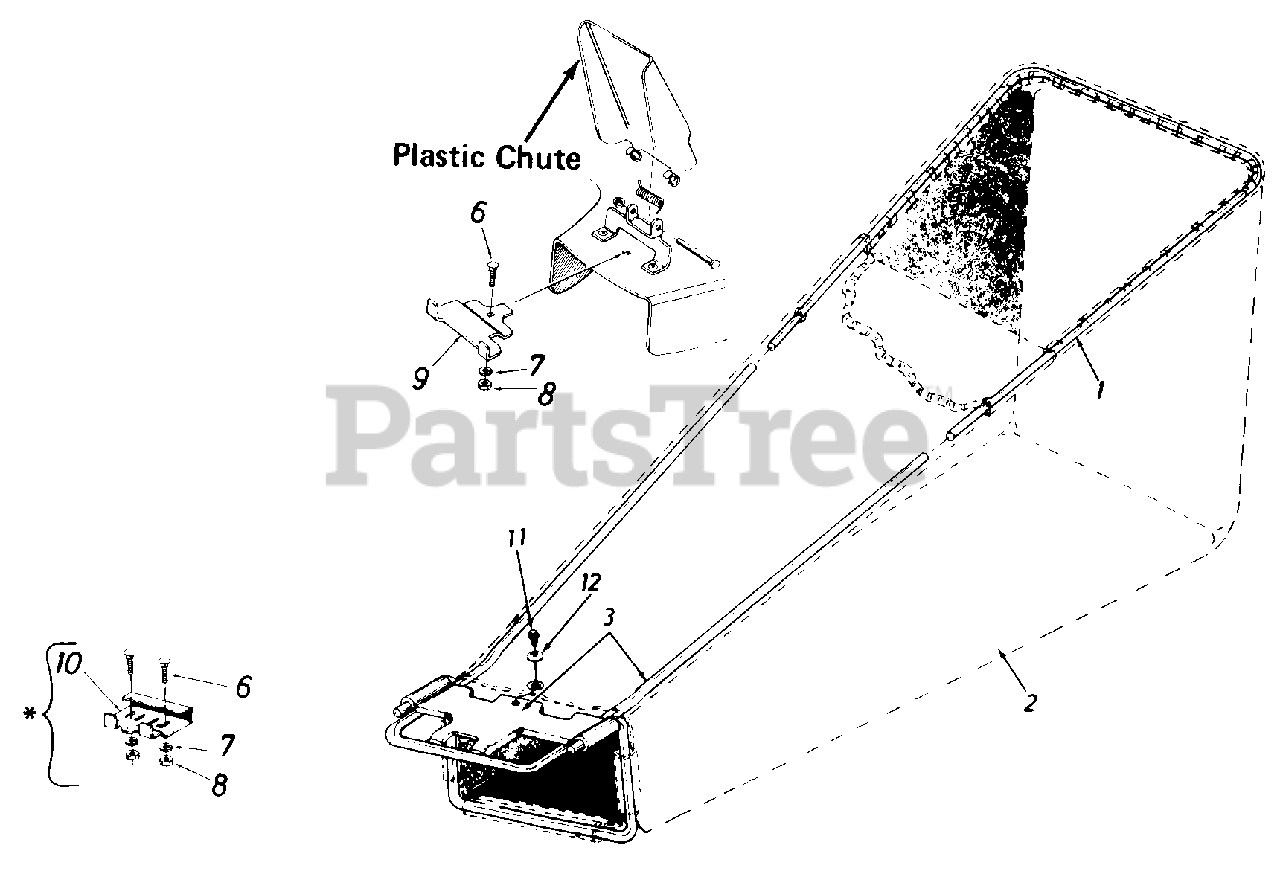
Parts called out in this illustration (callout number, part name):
1	Frame- Upper
2	Grass Catcher Bag
3	Frame- Lower
6	Carriage Bolt
7	Lock Washer 1/4" I.D.*
8	Hex Nut 1/4-20 Thd.*
9	Adapter Plate
10	Adapter Plate
11	Self-Tap Scr. 1/4" x 1/2" Lg.
12	Bell-Wash. 1/4" I.D.
